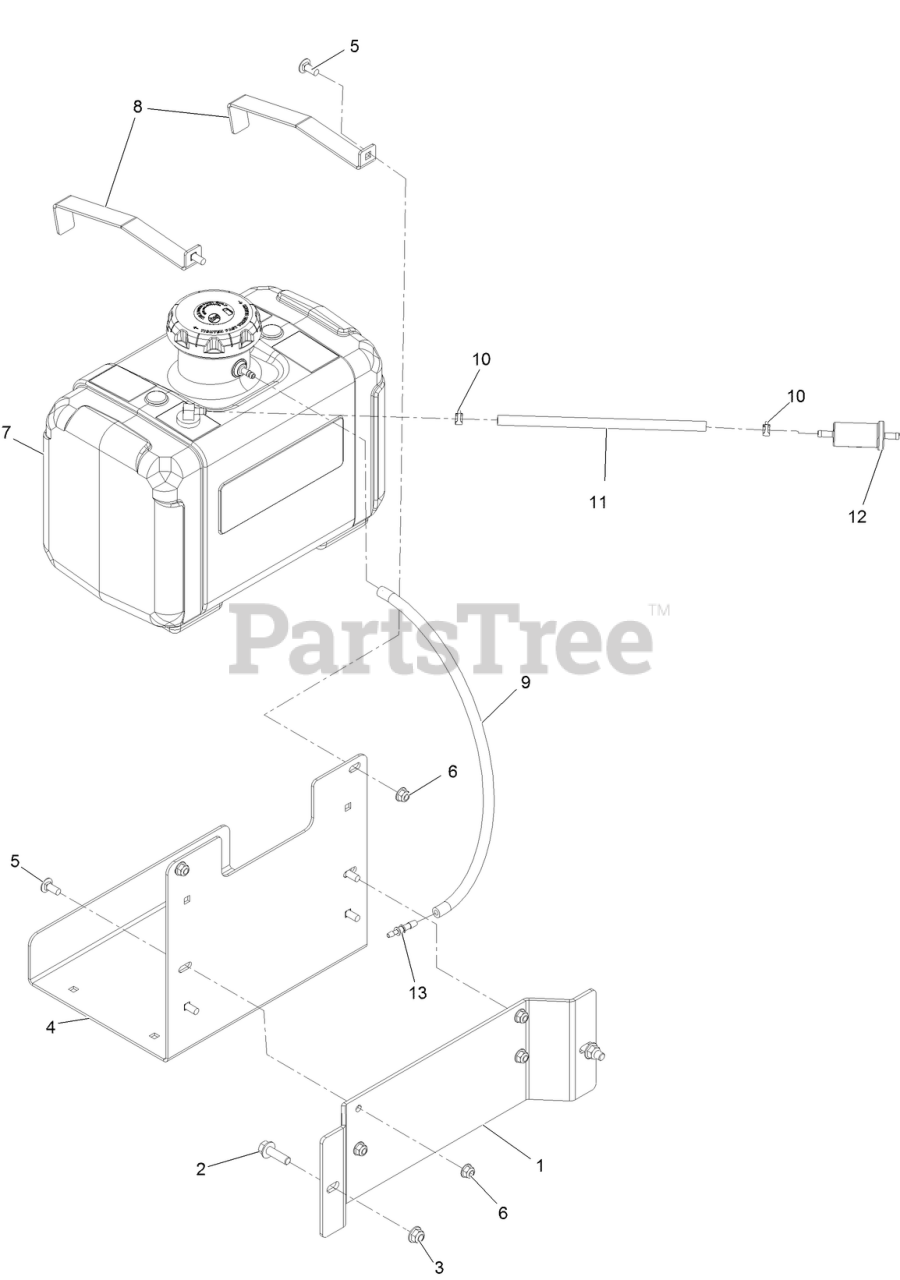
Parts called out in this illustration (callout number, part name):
1	MOUNT, GAS TANK, AE
2	SCREW-HHF
3	NUT-HF, NI
4	Mount-Tank,Bracket
5	SCREW-CARR
6	NUT-HF, NI
7	ASM-Tank, 5 Gal.
8	Strap-Tank, Ae
9	HOSE-FUEL
10	CLAMP-HOSE
11	HOSE-FUEL
12	FILTER-FUEL
13	BARB-FUEL
